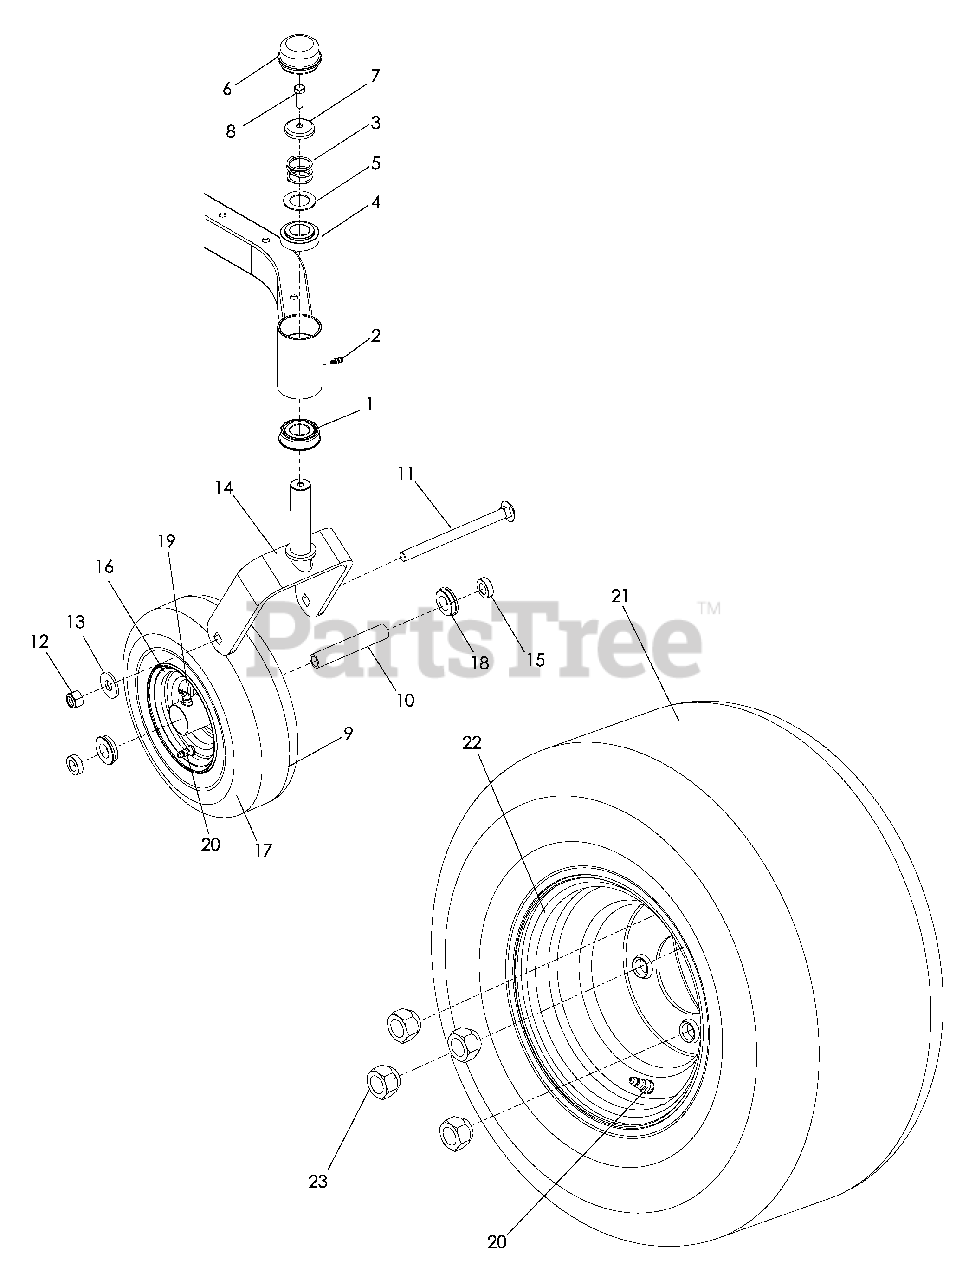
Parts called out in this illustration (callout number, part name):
1	BEARING, FLANGED
2	ZERK 3/16 DRIVE
3	SPRING, CASTER
4	BUSHING, CASTER
6	GREASE CAP
7	PLUG, CASTER
8	HCS 5/16-18 x 1
9	CASTER TIRE ASSM
11	RHSNB ½-13 x 6½
12	NUT ½ HEX NYLOC
13	WASHER ½ FLAT
14	YOKE
15	SPACER 5/16
17	CASTER TIRE, 410/350 4 PLY
18	BEARING, FLANGED
19	ZERK
20	VALVE STEM
21	TIRE, REAR ASSM 20 x 8 965880401, 966038501, 966038201
22	RIM 8 x 7 w/ .8" OFFSET
23	NUT, LUG ½
